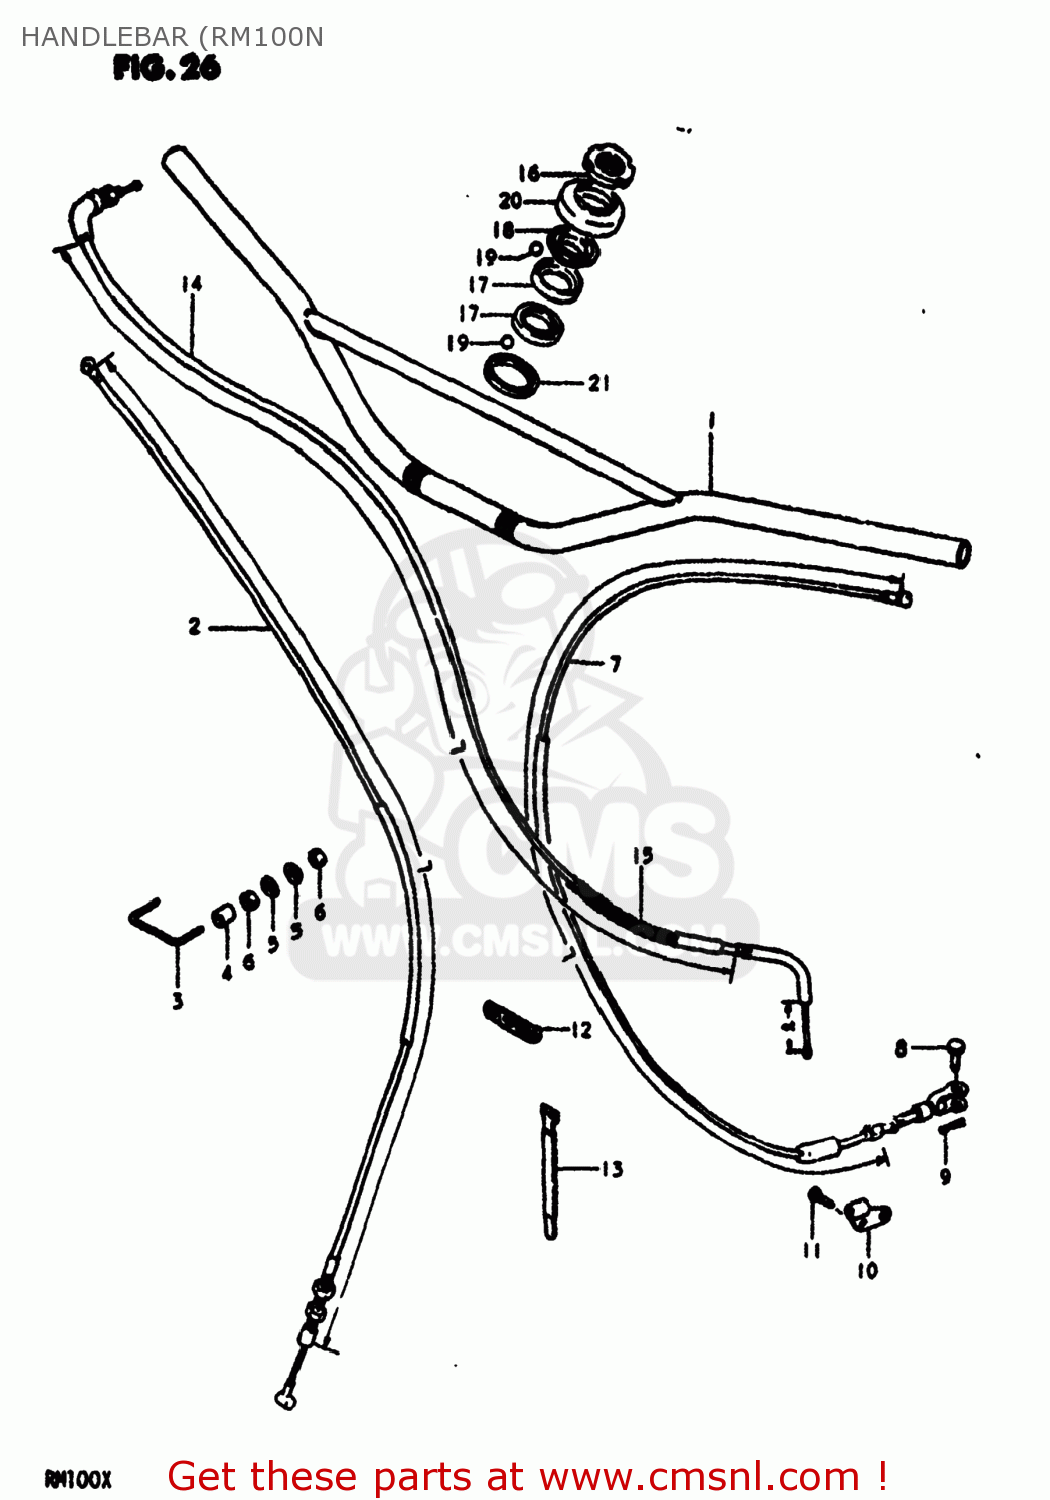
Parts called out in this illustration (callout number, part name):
1	HANDLEBAR
2	CABLE,FRONT BRAKE
3	CLAMP,CABLE
4	BUSHING
5	WASHER
6	NUT 3MM
7	CABLE ASSY,CLUTCH
8	PIN(L:13)
9	PIN
10	STOPPER,CLUTCH CABLE
11	SCREW
12	CLAMP L:35
13	CLAMP
14	CABLE ASSEMBLY,THROTTLE
15	PROTECTOR,CABLE
16	NUT,STEERING STEM
17	RACE,STEERING,INNER,UPPER
18	RACE,STEERING,OUTER,UPPER
19	BALL
20	SEAL,STEERING UPR DUST
21	DUST SEAL,STEERING HEAD
